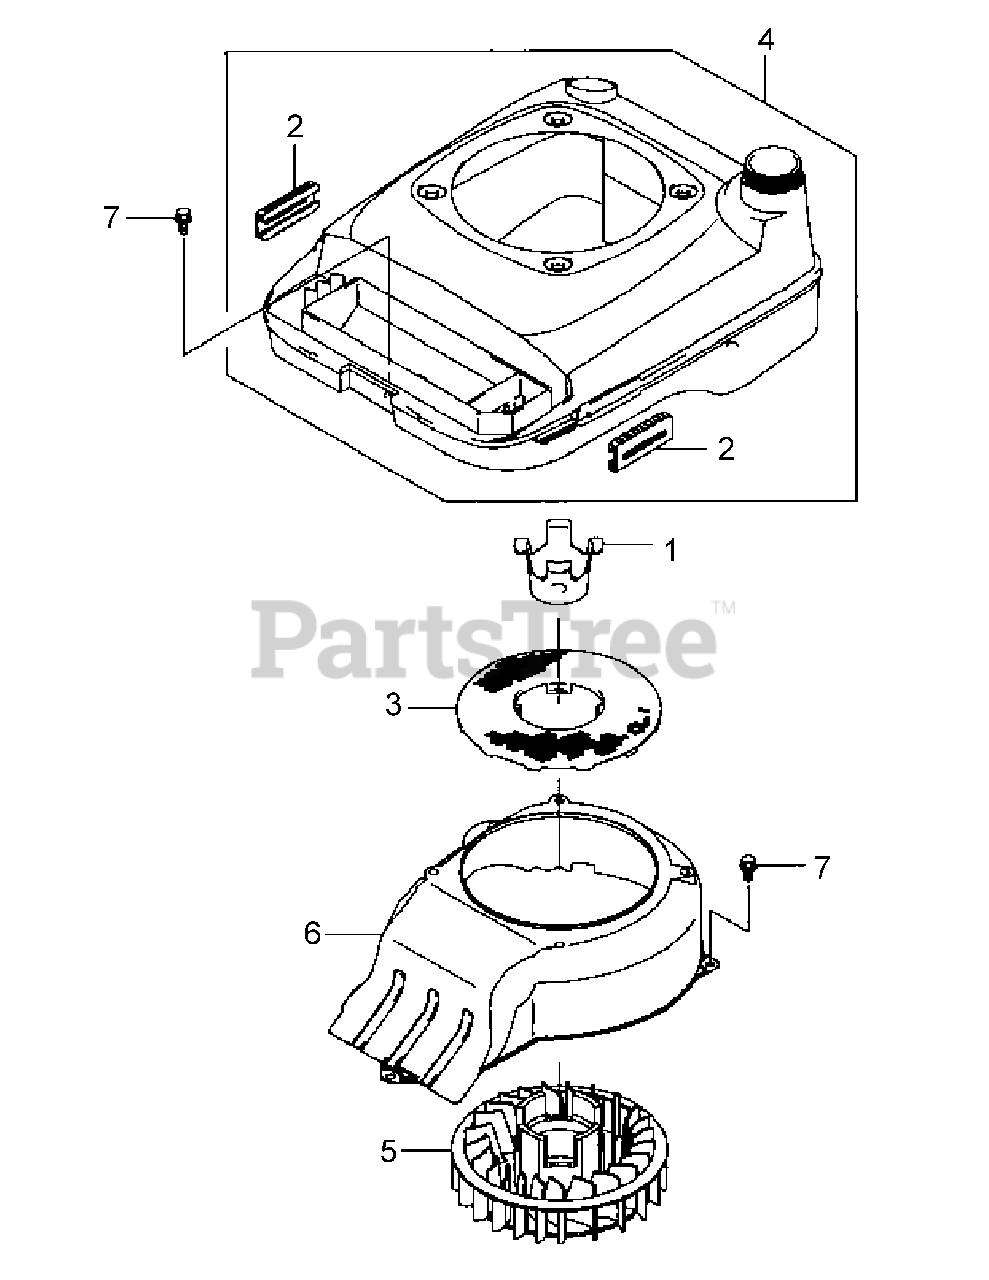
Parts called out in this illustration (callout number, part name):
3	Screen
4	Cover
5	Fan
6	Fan Housing
7	Flanged Bolt
